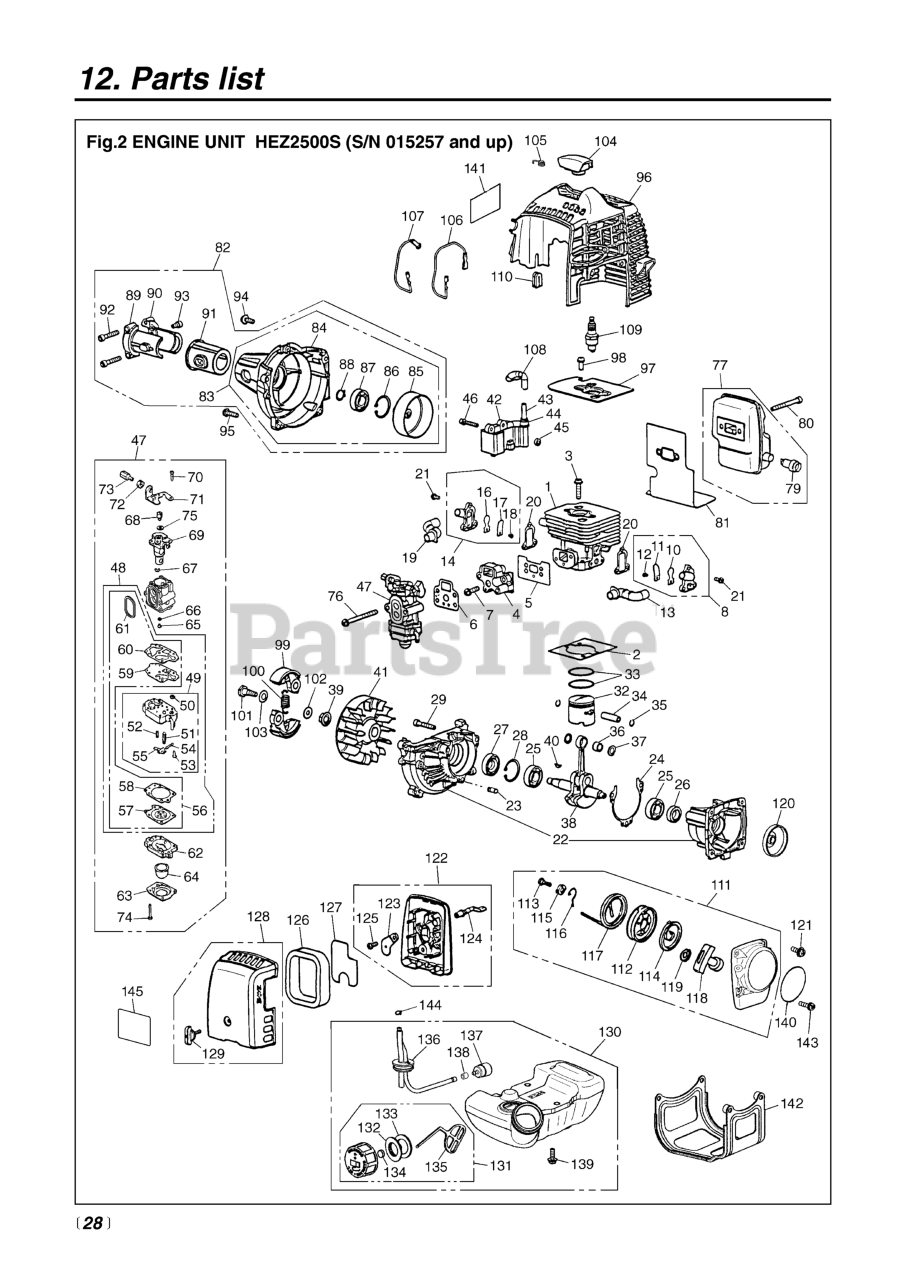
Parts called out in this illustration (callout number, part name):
1	CYLINDER (RPLS. 4810-12111)
2	GASKET, BASE
3	BOLT, M5 X 22
4	INSULATOR (RPLS. -13160/13161)
5	GASKET, INSULATOR
6	GASKET, CARBURETOR
7	SCREW, M5X20 (RPLS.1400-75510)
8	REED VALVE (RPLS 4810-16110)
10	VALVE, REED
11	STOPPER
12	SCREW, M3 x 8
13	PIPE, AIR
14	REED VALVE (F) (RPLS. -1611)
16	VALVE, REED
17	STOPPER
18	SCREW, M3 x 8
19	PIPE, AIR (F)
20	GASKET, VALVE
21	SCREW
22	CRANKCASE COMP (USE 4810-21101
23	PIN
24	GASKET
25	BEARING
26	SEAL
27	SEAL, OIL (RPLS 1140-21220)
28	RING, SNAP, M28 x 1.2
29	BOLT, M5 X 30
32	PISTON
33	RING, PISTON
34	PIN
35	RING, SNAP (RPLS 1101-41320)
36	BEARING (RPLS 1140-41330)
37	WASHER
38	CRANKSHAFT COMPLETE
40	KEY
41	ROTOR
42	COIL-A
43	CORD
44	CAP
45	SPACER (RPLS -71260)
46	BOLT, M4 x 22
47	CARBURETOR ASSY.
48	REBUILD KIT
49	BODY-A
50	SCREEN
51	VALVE
52	SPRING
53	SCREW
54	PIN
55	LEVER
56	KIT, GASKET (REPLACES-06020)
57	DIAPHRAGM
58	GASKET, DIAPHRAGM
59	DIAPHRAGM, PUMP
60	GASKET, PUMP
61	RING
62	BODY, PURGE
63	COVER, PUMP
64	PUMP, PRIMING
65	JET
66	RING, O
67	RING
68	SWIVEL
69	VALVE
70	SCREW
72	NUT, CABLE ADJUSTER
73	SCREW, CABLE ADJUSTER
74	SCREW
75	WASHER
76	SCREW, M5 x 60
77	MUFFLER ASSEMBLY
79	ARRESTER
80	BOLT, M5 x 50
81	GASKET (RPLS T1501-15210)
82	COVER ASSY. (REPLACES -31001)
83	COVER COMP. (REPLACES -31101)
84	COVER, FAN (REPLACES -31110)
85	DRUM (REPLACES 4810-31122)
86	RING, SNAP, M28 x 1.2
87	BEARING
88	RING, SNAP (RPLS 3130-13270)
89	BRACKET (A) (RPLS -31210)
90	BRACKET (B) (REPLACES -31220)
91	CUSHION
92	BOLT, M5 X 30
93	BOLT (USE 3310-31720)
94	SCREW
95	SCREW, M5X20 (RPLS.1400-75510)
96	COVER, ENGINE (RPLS -32110)
97	PLATE
98	SCREW, M5 X 10
99	SHOE
100	SPRING
101	BOLT
102	WASHER, FLAT (USE 182303)
103	WASHER (RPLS -51241)
104	CAP (RPLS 4810-72110)
105	SPRING
106	CORD (BLACK)
107	CORD, EARTH (RED)
108	TUBE
109	PLUG, SPARK (RPLS 4810-73110)
110	GROMMET
111	RECOIL ASSEMBLY
112	REEL
113	SCREW
114	SPRING, SPIRAL
115	COLLAR
116	ARM
117	ROPE (REPLACES 4500-75160)
118	KNOB (RPLS -75420)
119	PLATE, STOPPER
120	PULLEY
121	SCREW
122	BODY ASSEMBLY
123	PLATE, CHOKE
124	LEVER, CHOKE
125	SCREW
126	ELEMENT
127	SCREEN
128	COVER ASSEMBLY
129	KNOB (RPLS -82220)
130	TANK ASSY (RPLS-85001)
131	CAP ASSY (RPLS -85201)
132	HOLDER (REPLACES -85230)
133	PACKING
134	FILTER
135	STOPPER
136	PIPE COMPLETE
137	FILTER ASSY
139	SCREW
140	LABEL, RECOIL
141	LABEL, COVER
142	GUARD (RPLS 4810-31911)
143	SCREW, M5 x 25
144	CLIP
